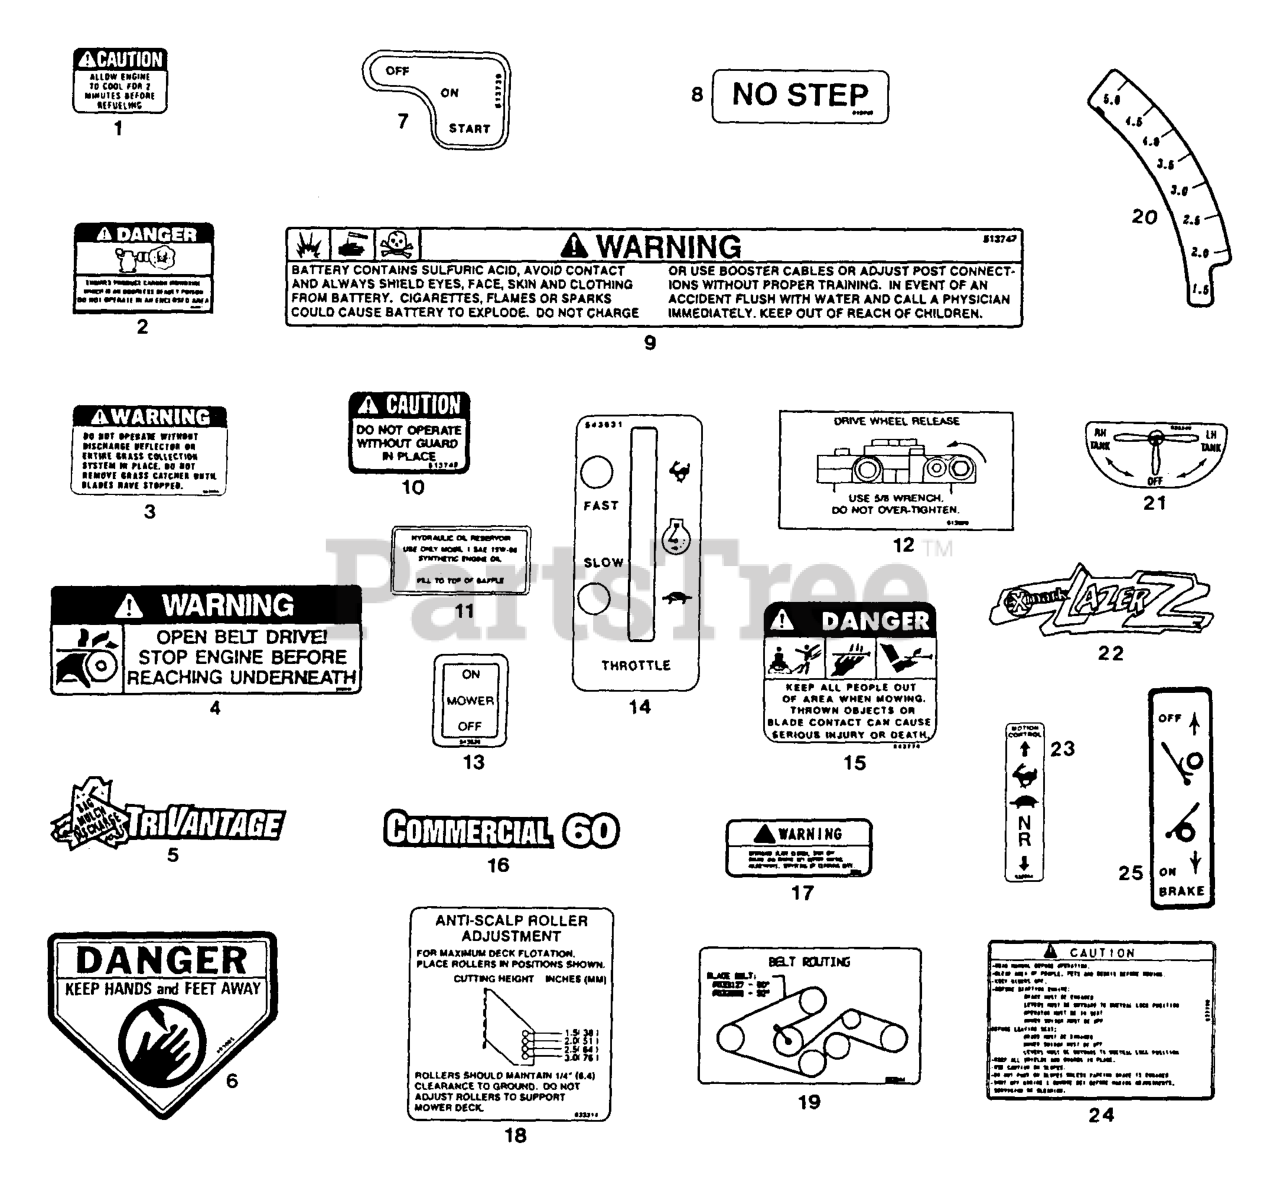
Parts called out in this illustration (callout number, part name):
3	DECAL-WARNING, DISCHARGE
4	DECAL,BELT DRIVE
6	DECAL-DANGER
8	DECAL,NO STEP
9	DECAL-BATTERY
10	DECAL-GUARD
11	DECAL,HYD TANK
13	DECAL-MOWER SWITCH
15	DECAL-DANGER
16	DECAL,COMMERCIAL 60
17	DECAL,WARNING
20	DECAL-HEIGHT, DECK
25	DECAL-LAZERZ BRAKE
